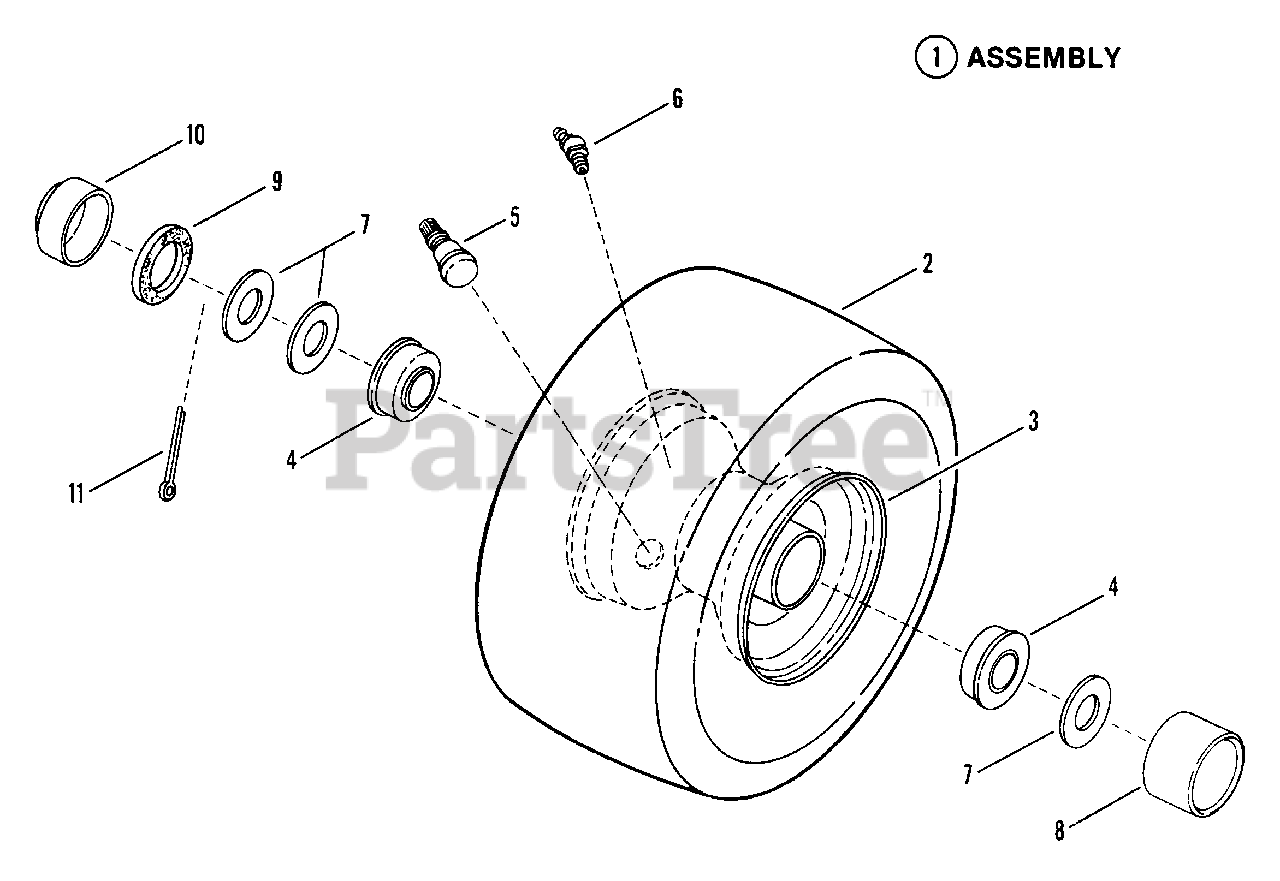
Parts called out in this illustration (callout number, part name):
1	ASSEMBLY, Front Tire & Rim (Complete)
1	ASSEMBLY, Tire & Rim
2	TIRE, 4.10/3.50 x 4
3	RIM
4	BEARING, Ball
5	VALVE, Air (Snap-in)
6	FITTING Lube
7	WASHER
8	CAP, Hub
9	SEAL, Felt
10	CAP, Dust
11	PIN, 5/32 x 1" Cotter
